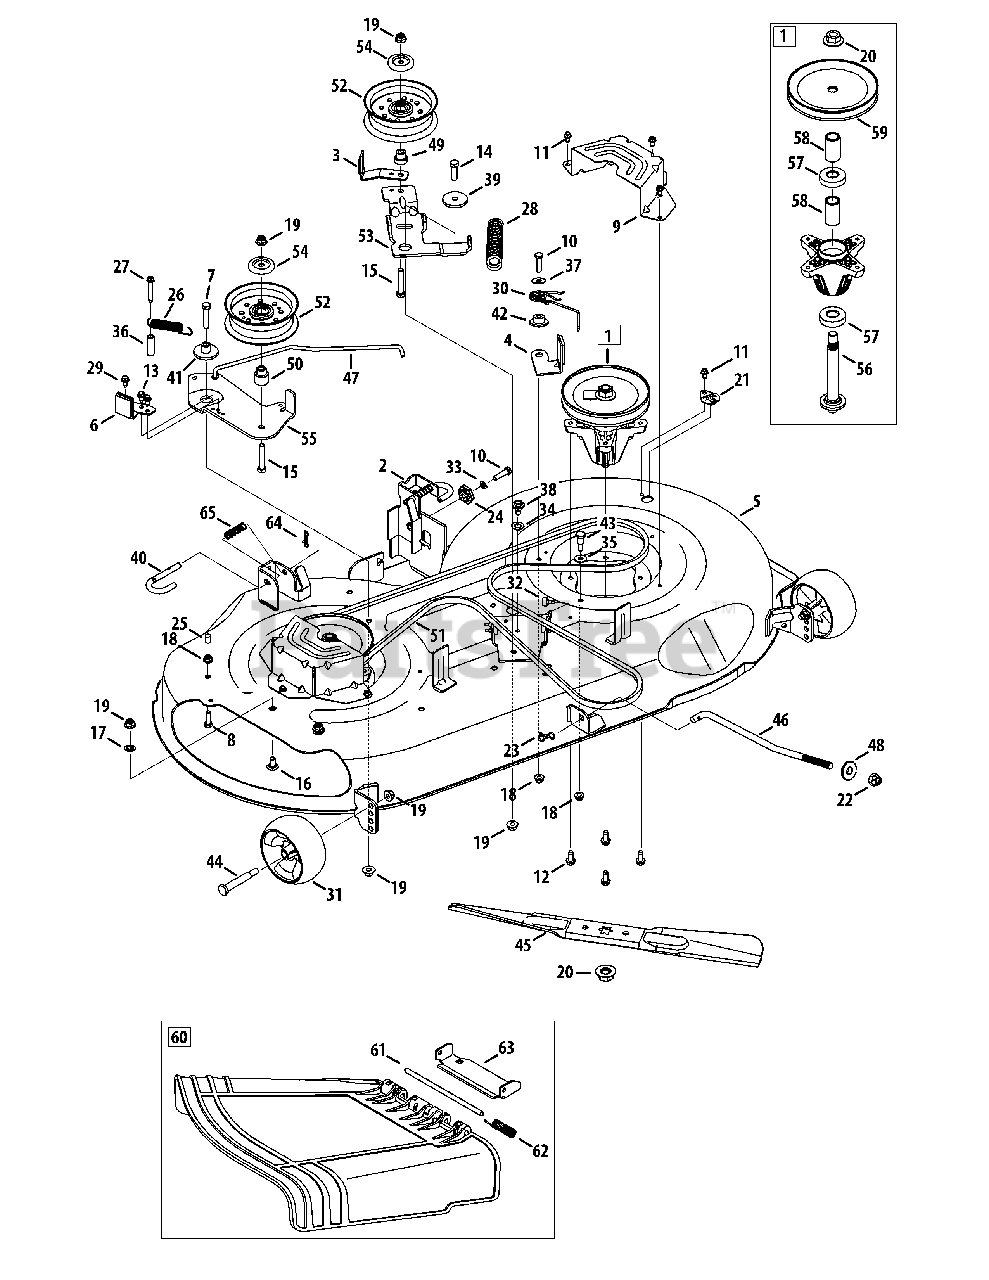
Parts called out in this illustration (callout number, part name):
1	Spindle Assembly, Pul 6.74 Dia
2	Bracket Assembly, Deck Hanger, LH
3	Belt Keeper
4	Brake Bracket Assembly, LH
6	Brake Bracket Assembly, RH
7	Hex Screw, 3/8-16 x 1.75
8	Hex Cap Screw, 5/16-18 x 1.00
9	Deck Belt Cover, 46
10	Hex Screw, 5/16-18, 1.25, Gr5, Std
11	Screw, Self-tapping, 1/4-20, 0.500
12	Screw, 5/16-18 x 0.750
13	Tap Screw, 1/4-20, 0.625
14	Hex Screw, 3/8-16 x 1.25
15	Hex Screw, 3/8-16 x 2.00
16	Bolt, Carriage, 3/8-16, 0.75, Gr1
17	Nut, Push, 3/8
18	Nut, Flange Lock, 5/16-18, Nylon
19	Nut, Flange Lock, 3/8-16, Nylon
20	Nut, Flange, 5/8-18
21	Deck Wash Plug
22	Nut, Lock, 1/2-13
23	Bow-Tie Cotter Pin
24	Gear, Deck Adjustment
25	Cap, .290 x .500
26	Extension Spring, .750 X 4.77
27	Screw, Self Tapping, 1/4-20, 1.50
28	Spring, Extension, 1.05 X 6.346
29	Shoulder Screw, 1/4-20
30	Torsion Spring, LH
31	Wheel, Deck, 5.0 Dia Ball
32	Bumper, .62 Dia X .3
33	Washer, Lock, 5/16, Regular Duty
34	Washer, Flat, .474 x .879 x .064
35	Washer, Flat, .343 X .880 X .062
36	Spacer, .260 x .375 x 1.030
37	Flat Washer, .344 x 1.0 x .063
38	Shoulder Spacer, .43 x .29, 5/16-18
39	Shoulder Spacer, .8840 X .190
40	Rod, Deck Release
41	Shoulder Spacer, .854 x .190
42	Shoulder Spacer, .75 x .145
43	Shoulder Screw, .437 Dia. X .54
44	Bolt, Shoulder, .496 x 2.50, 3/8-16
45	Blade, Cut, 23.25" 2-In-1, Econ
46	Rod, Lift, Deck, Medium
47	Brake Rod
48	Pivot Cup, Deck List
49	Shoulder Spacer, Idler
50	Shoulder Spacer, Pivot Idler
51	Belt, V-Typ, A Sec
52	Pulley, Idler, 4.50"Dia
53	Bracket, Idler, 46" Lh
54	Pulley Cap
55	Deck Idler Bracket
56	Spindle Shaft, 6.05 LG.
57	Ball Bearing, .787ID X 1.85 ODX.551
58	Spacer, .792 X 1.060 X 1.860 LG
59	Deck Pulley, 6.74 DIA
60	Chute Deflector Assembly
61	Hinge Pin
62	Torsion Spring
63	Chute Bracket
64	Bow-Tie Cotter Pin, 72
65	Spring, Compression, .535 x 1.751
